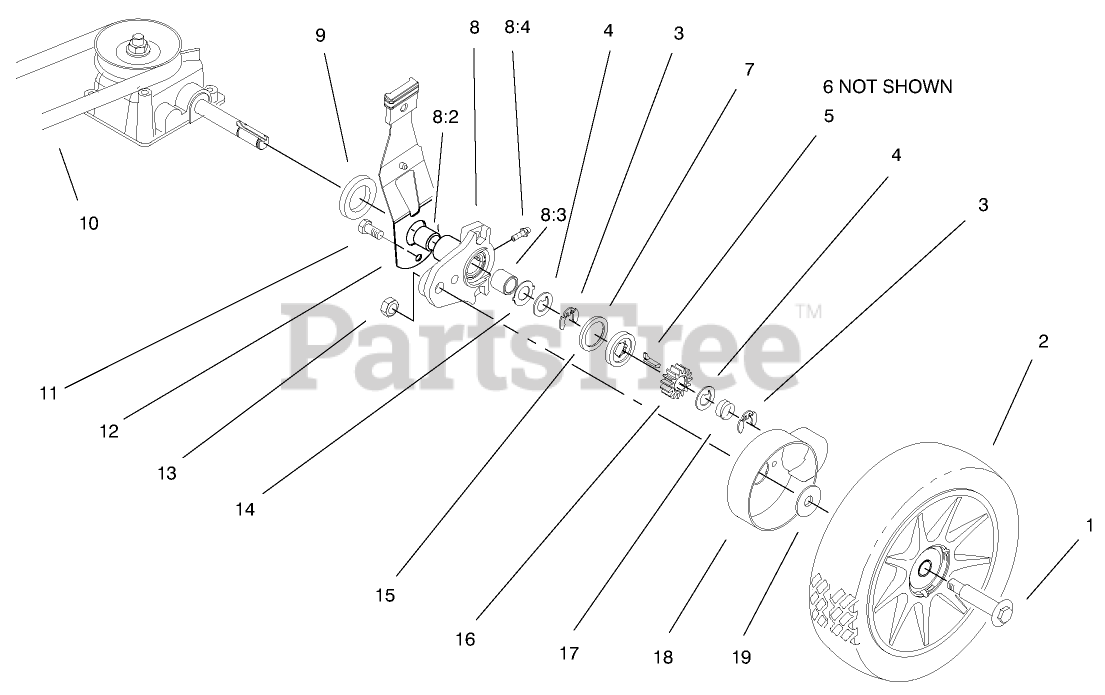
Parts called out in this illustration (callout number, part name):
1	BOLT-SHOULDER
2	WHEEL AND TIRE ASM
3	RING-RETAINING,CLIP
4	WASHER-THRUST, KEYED
5	KEY-ROCKING, LH
6	KEY-ROCKING, RH
7	RING-FRICTION
8	REAR HEIGHT ADJUSTMENT ARM ASM
9	SPACER-SHAFT, AXLE
10	V-BELT
11	SCREW-HWH
12	REAR SPRING ARM ASM
13	NUT-JAM, LOCKING
14	WASHER-ARM, PIVOT
15	WASHER-CLUTCH
16	GEAR-PINION
17	SPRING-COMPRESSION
18	COVER-WHEEL
19	WASHER-STEPPED
20	KNOB-LEVER, HEIGHT ADJUSTMENT
